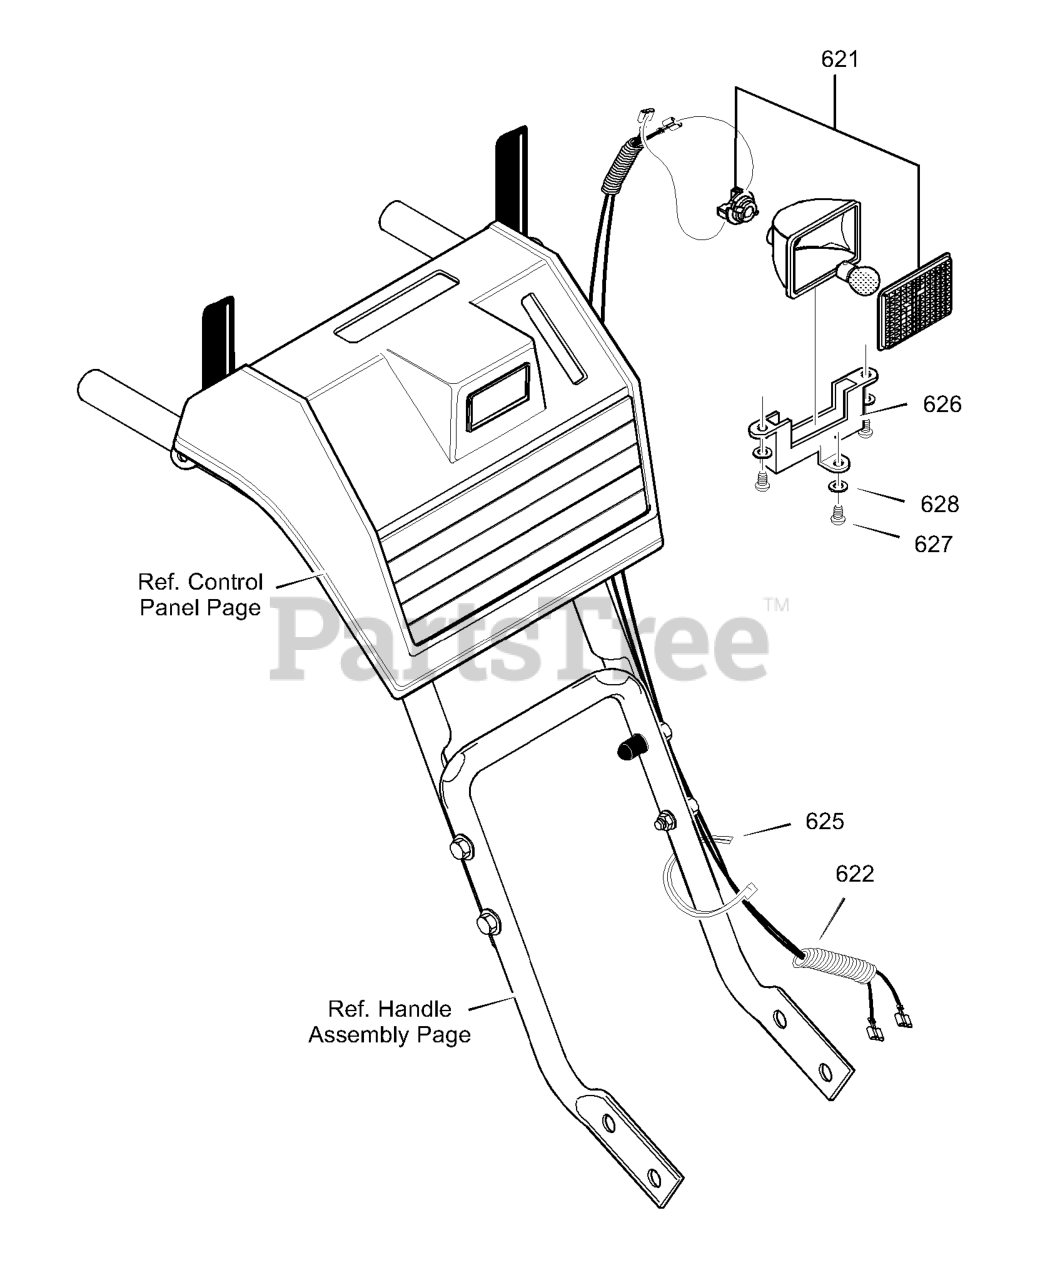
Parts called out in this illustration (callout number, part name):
621	HEADLIGHT ASSY
622	HARNESS ASSY, WIRE
625	CABLE TIE
626	BRACKET, HEADLAMP
627	SCREW, #8 x .50
628	WASHER, FLAT
